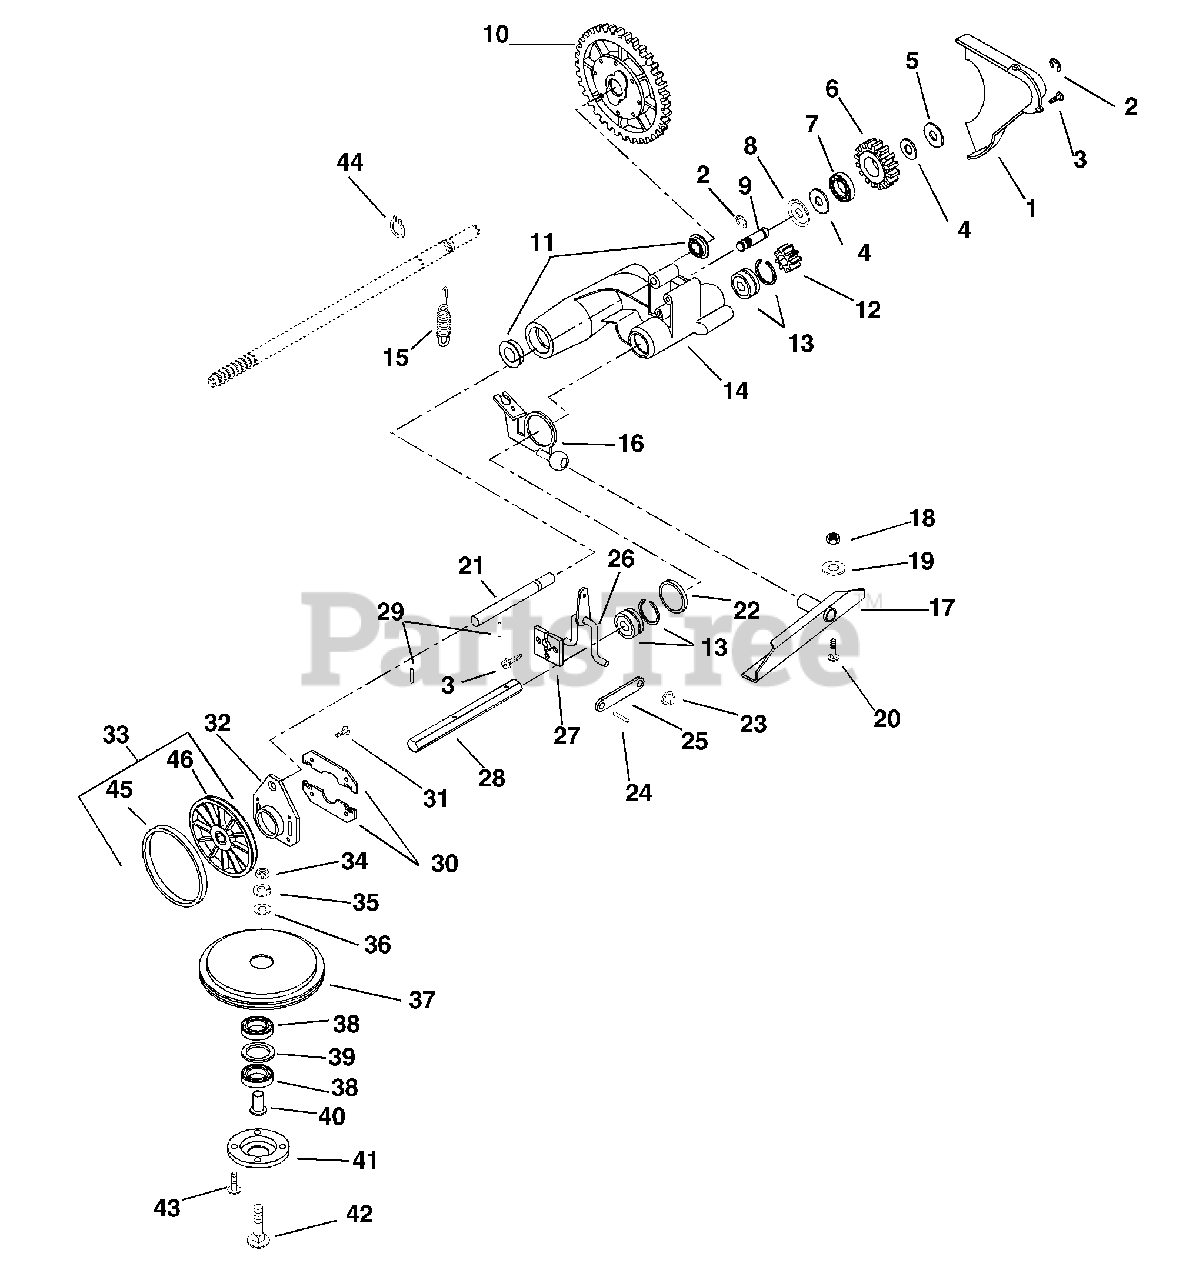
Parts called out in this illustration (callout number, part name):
1	COVER, DRIVE
2	RG-RTNG-EXT .438X.035
3	@SCR-TAP 12-24X.50 HWH TR YWZC
4	WSHR-FL-STL .52X.827X.062 YWZC
5	WSHR-FL-STL.531X1.00X.063 YWZC
6	IDLER GEAR
7	BRG-BALL .500X1.38X.437
8	RETAINER
9	IDLER SHAFT
10	DIFFERENTIAL ASSEMBLY
11	BRG-BALL .625X1.383X.50
13	BRG-BALL .562X1.375X.437
14	DRIVE MOUNT
15	SG-TENS .051X.60X2.25 WLD 7.0
16	DRIVE ACTUATOR WELDMENT
17	PIVOT, CHANNEL WELDMENT
18	@NUT-LK-CTR .31-18 YWZC
19	@WSHR-FL-STL.344X.688X.065YWZC
20	@BLT-RHDSSQNK .31-18X.62 G5YZ
21	ROD - GUIDE
22	WSHR-FL-STL 1.390X2.00X.020 PL
23	PUSH NUT, .25
24	PIN-ROLL .125X.50
25	SHIFT LINK
26	SHIFT ARM WELDMENT
27	RETAINER PLATE
28	HEX SHAFT
29	PIN-ROLL .188X.88
30	THRUST PLATE
31	@SCR-TAP 10-24X.375 HWH YZ TR
32	GUIDE PLATE
33	FRICTION WHEEL ASSEMBLY
34	@NUT-HEX .31-18 YWZC
35	WSHR-LK .312X.097 HVY YWZC
36	WSHR-FL-STL .328X.875X.062YWZC
37	FRICTION SHEAVE
38	BRG-BALL .625X1.375X.43
39	WSHR-FL-STL 1.062X1.344X.032PL
40	SPINDLE - BEARING
41	RETAINER - BEARING
42	@BLT-RDHDSQNK .31-18X1.75 G5YZ
43	@SCR-TAP 12-24X.50 HWH TR YWZC
44	RG-RTNG-EXT .625X.035
45	FRICTION RING
46	FRICTION WHEEL HUB
